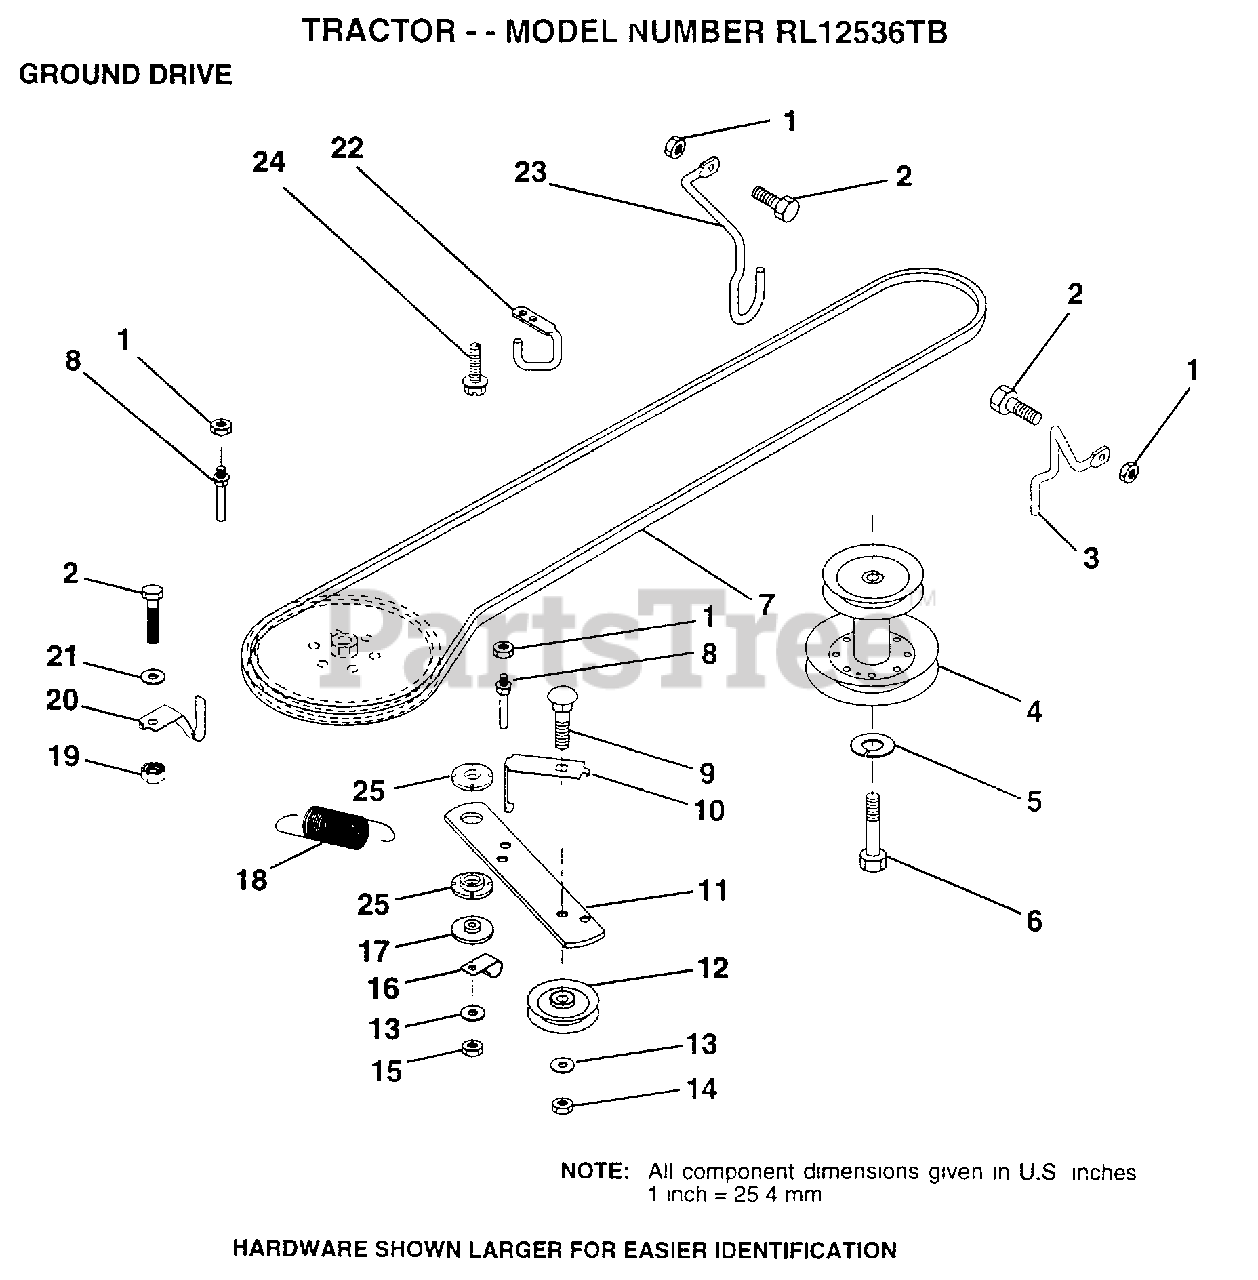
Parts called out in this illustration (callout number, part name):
2	BOLT
3	KEEPER RH
4	PULLEY.ENGINE.LR
5	LOCKWASHER
6	HEX BOLT
7	BELT
8	"KEEPER,DRIVE BELT"
9	BOLT
10	"KEEP,IDLER DR BEL"
11	ARM-IDLER.DR.GRND
12	PULLEY.IDLER.FLAT
13	WASHER
14	LOCKNUT
16	"CLIP,INSULATOR"
17	SPACER
20	KEEPER.BELT.T/A
21	WASHER
22	"KEEPER,FRA DR BEL"
23	KEEPER MOWER LH
24	SCREW
25	BUSHING.NYLON
